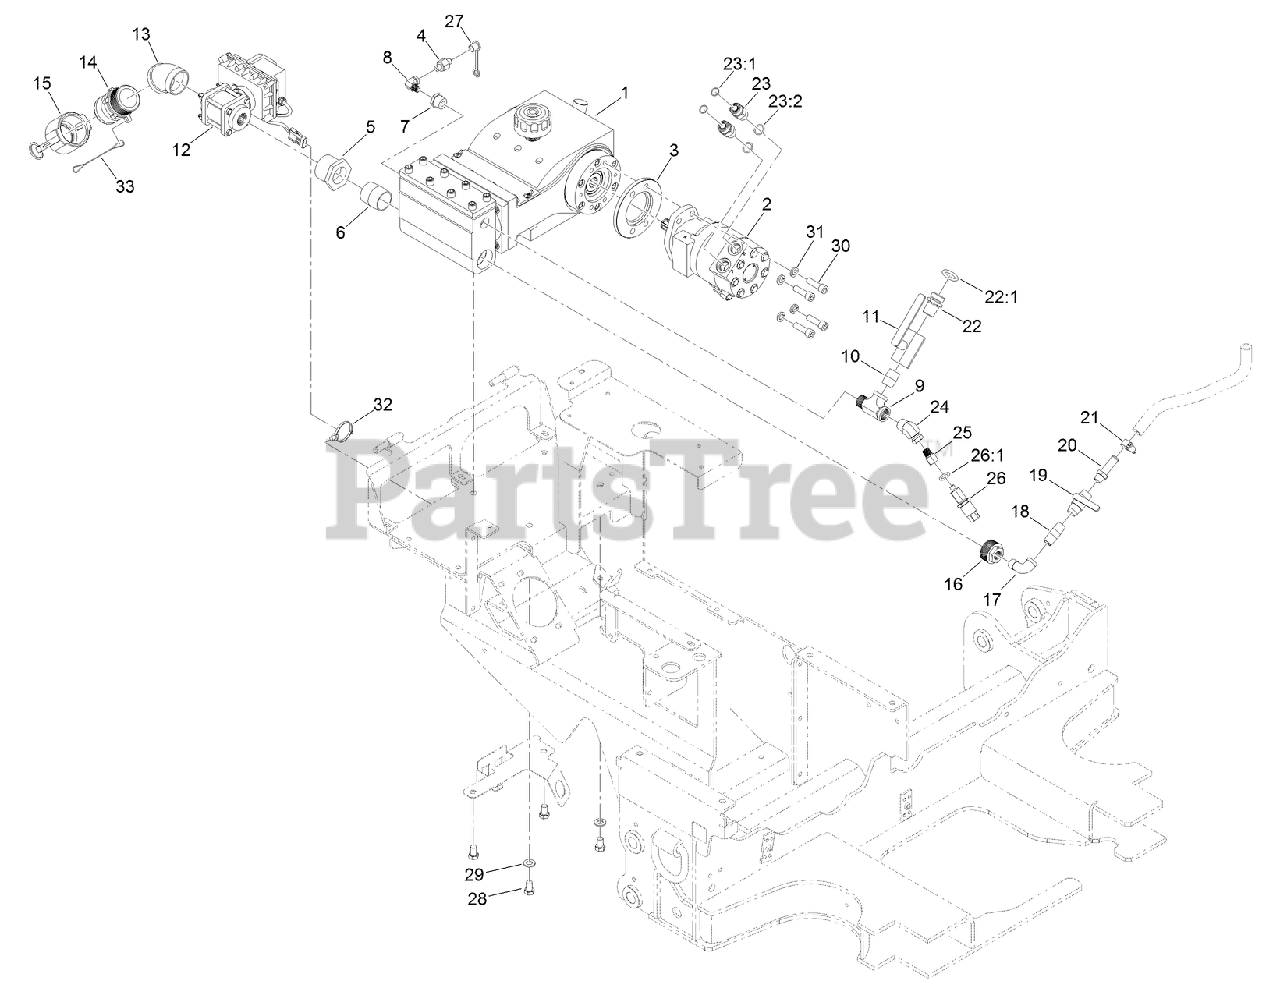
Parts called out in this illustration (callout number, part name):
1	MUD PUMP ASM
2	MOTOR-HYDRAULIC
3	SPACER
4	NIPPLE-CONNECT, QUICK
5	NIPPLE-PIPE
6	BUSHING-REDUCER
7	BUSHING-REDUCER
8	FITTING-ELBOW-90
9	FITTING-TEE
10	NIPPLE-STRAIGHT
11	VALVE-BALL
12	2 INCH BALL VALVE ASM (ELECTRIC)
13	ELBOW-PIPE-45
14	ADAPTER-MALE
15	CAP-CONNECT, QUICK
16	BUSHING-PIPE, REDUCER
17	FITTING-ELBOW-90
18	NIPPLE-PIPE
19	VALVE-BALL
20	ADAPTER
21	CLAMP-HOSE, WORM DRIVE
22	FITTING-STRAIGHT
22:1	O-RING
23	FITTING-STRAIGHT
23:1	O-RING
23:2	O-RING
24	FITTING-ELBOW-45
25	FITTING-STRAIGHT
26	TRANSDUCER (W/ISOLATOR)
26:1	O-RING
27	CAP-DUST
28	BOLT-HH
29	WASHER-FLAT
30	SCREW-HSH
31	SCREW-HH
32	CLIP-TIE
33	LANYARD-TETHER, PIN
